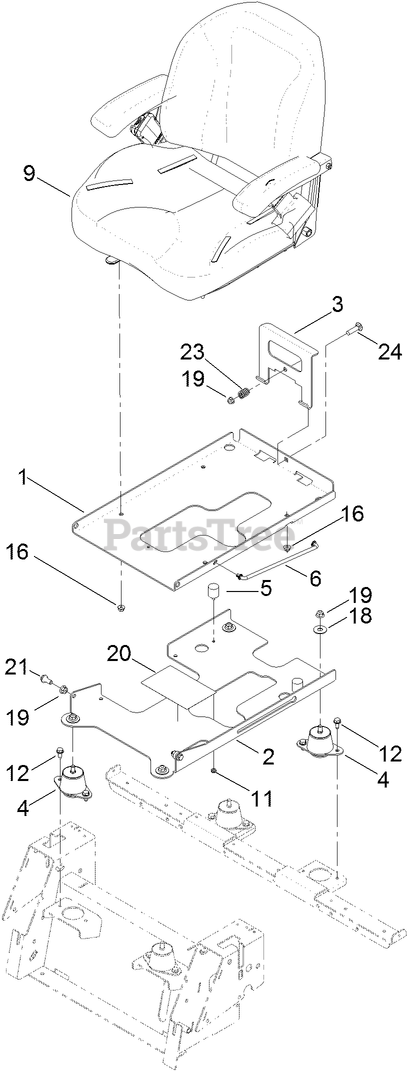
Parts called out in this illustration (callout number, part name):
1	PLATE-PAN, SEAT
2	PLATE-BASE
3	LATCH-SEAT
4	ISOLATOR-SEAT
5	BUMPER
6	ROD-PROP
9	SEAT ASM
11	NUT-LOCK, NI
12	SCREW-HWHTF
16	NUT-HF, NI
18	WASHER-FLAT
19	NUT-HF, NI
20	DECAL-MAINTENANCE
21	BOLT-SHOULDER
23	SPRING-COMPRESSION
24	SCREW-CARR
